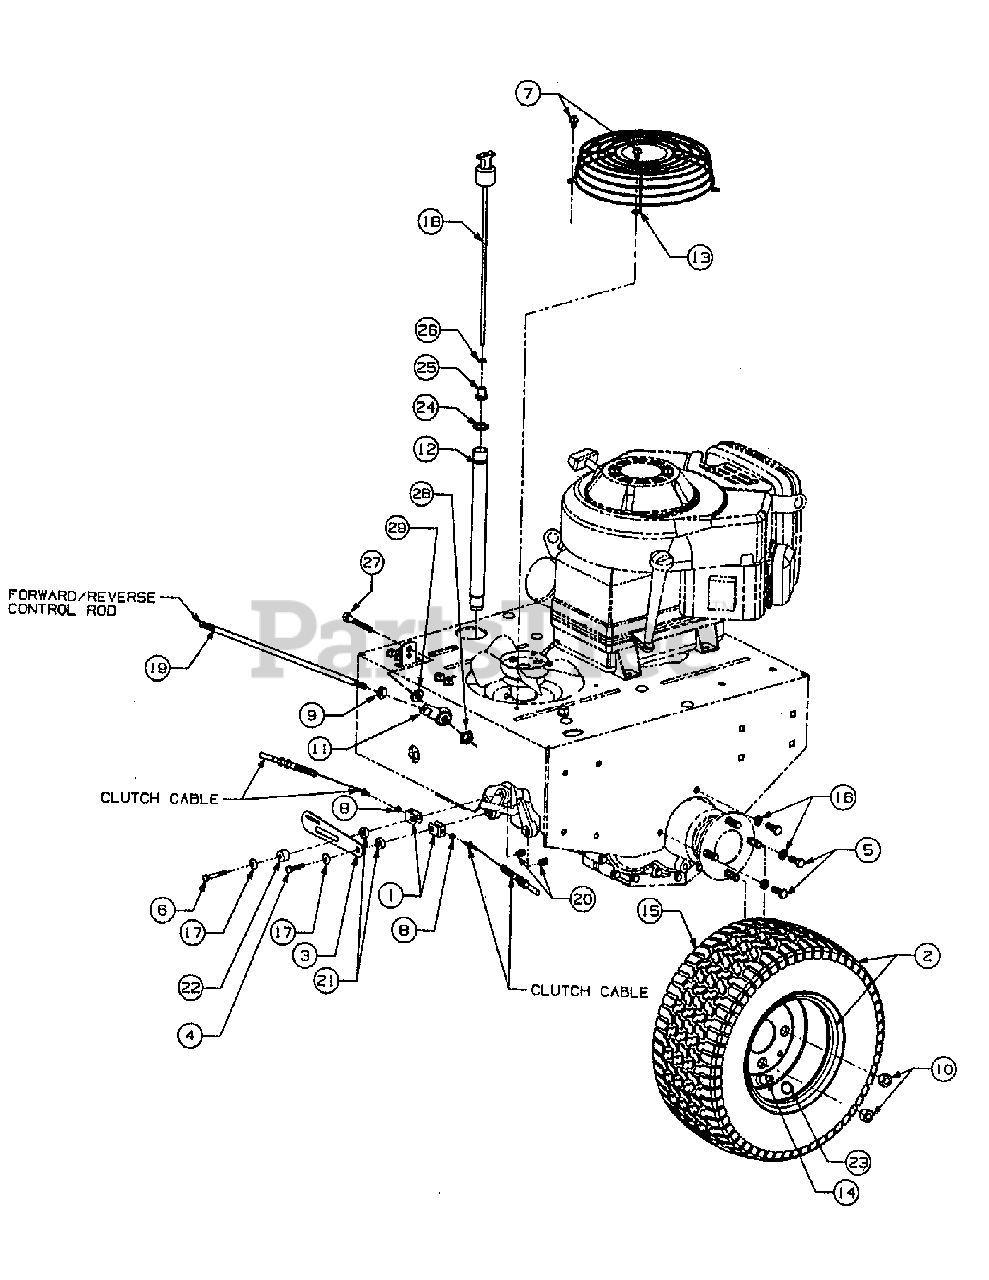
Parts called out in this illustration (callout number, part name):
1	U-Clevis,Clutch Cable
2	Wheel & Tire Assembly, 16 x 7.5-8
3	Plate, Parking Brake Switch Mount
4	Screw, Hex Cap,1/4-28 x 1.25 Gr 5
5	Screw, Hex Cap,3/8-16 x 1.0 Gr 5
6	Screw, Hex Cap, 1/4-28 x 1.75 Gr 5
7	Screw, Hex Wash Hd Tapp, 5/16-18 x .50
8	Nut, Hex Jam, #10-32
9	Nut, Hex Jam, 3/8-24 Gr 5
10	Nut, Lug, 1/2-20
11	Rod End, Spherical
12	Tube, Oil Fill
13	Guard, Fan Cover
14	Valve, Tubeless Air
15	Tire, Turf Chief, 16 x 7.5-8
16	Washer, Lock 3/8
17	Washer, Bell, .265 x .75 x .062 Thk
19	Rod, F/R Control
20	Nut, Clevis Spacer, 1/4-28
21	Spacer, Clevis
22	Spacer, Switch Engagement
23	label, Inflation
25	Seal, Rubber
26	Washer, Plain 5/16
27	Screw, Hex Cap 3/8-16 x 1.25
28	Nut, Flanged Lock, 3/8-16
29	Washer, Flat .407 x .812 x .135 HDN
